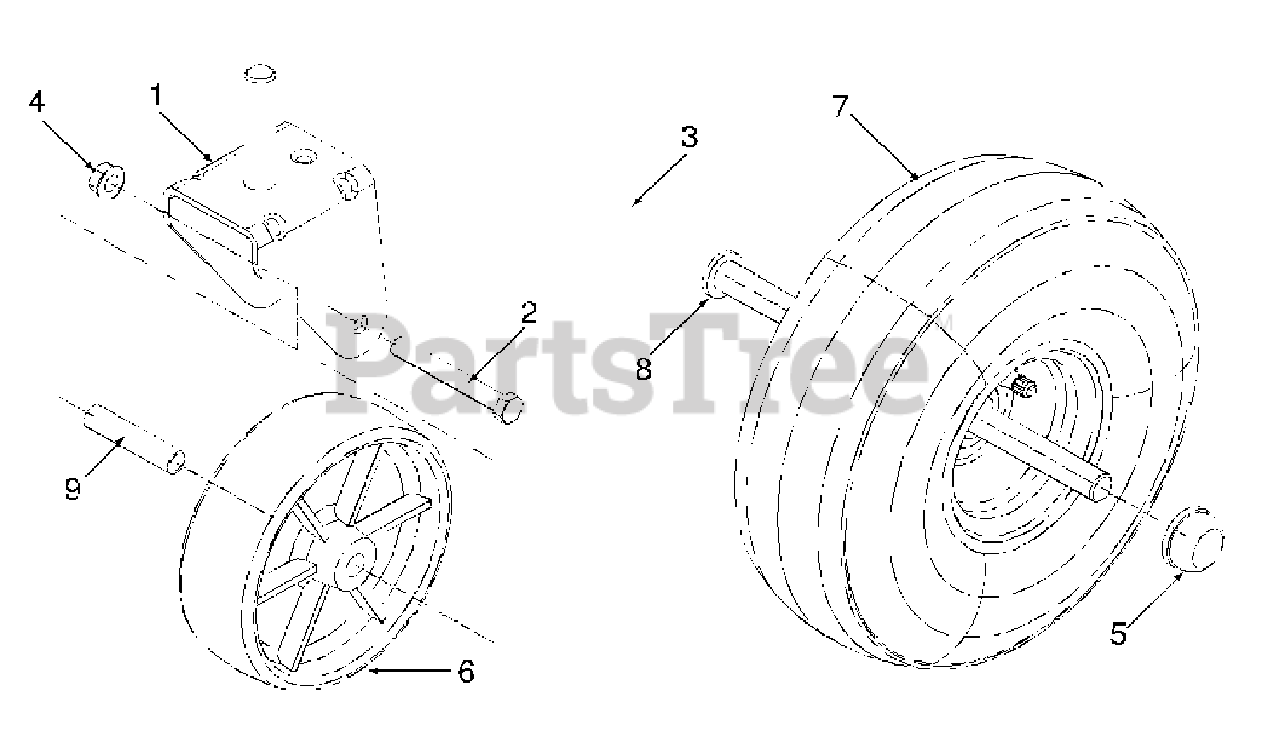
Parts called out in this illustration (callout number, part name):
2	HEX CAP SCREW 3/8-16 3.00
3	RR AXLE SHAFT
4	FLANGED LOCK NUT 3/8-16
5	PUSH CAP 5/8
6	WHEEL 6.00 x 2.00
7	WHEEL COMPLETE 10 x 4 x 4
8	FLAT WASHER 5/8 id x 1.00 od
9	SPACER .384 id x .500 od x 2.3
